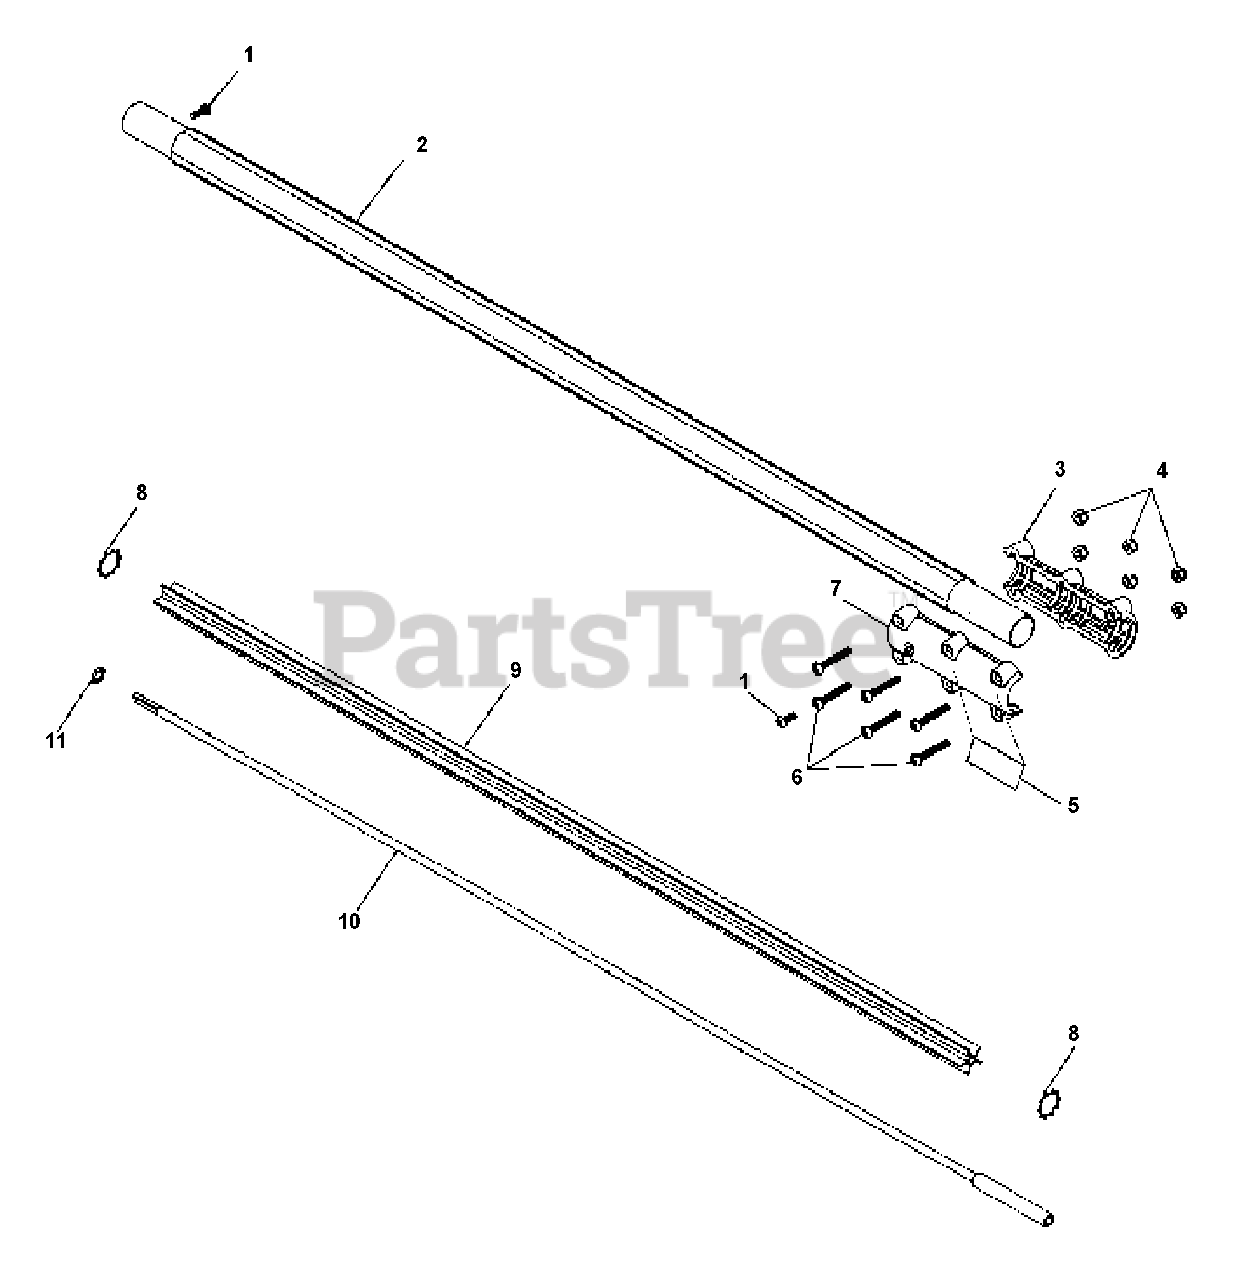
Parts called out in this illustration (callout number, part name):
1	SCREW
2	PIPE, MAIN
3	COLLAR, MAIN PIPE
4	LOCKNUT - 10-24
5	LABEL - CAUTION
6	SCREW - 10-24 X 1-1/4"
7	COLLAR, MAIN PIPE
8	LOCKWASHER - EXTERNAL
9	LINER - FLEXIBLE
10	DRIVESHAFT
11	LOCKWASHER - INTERNAL
